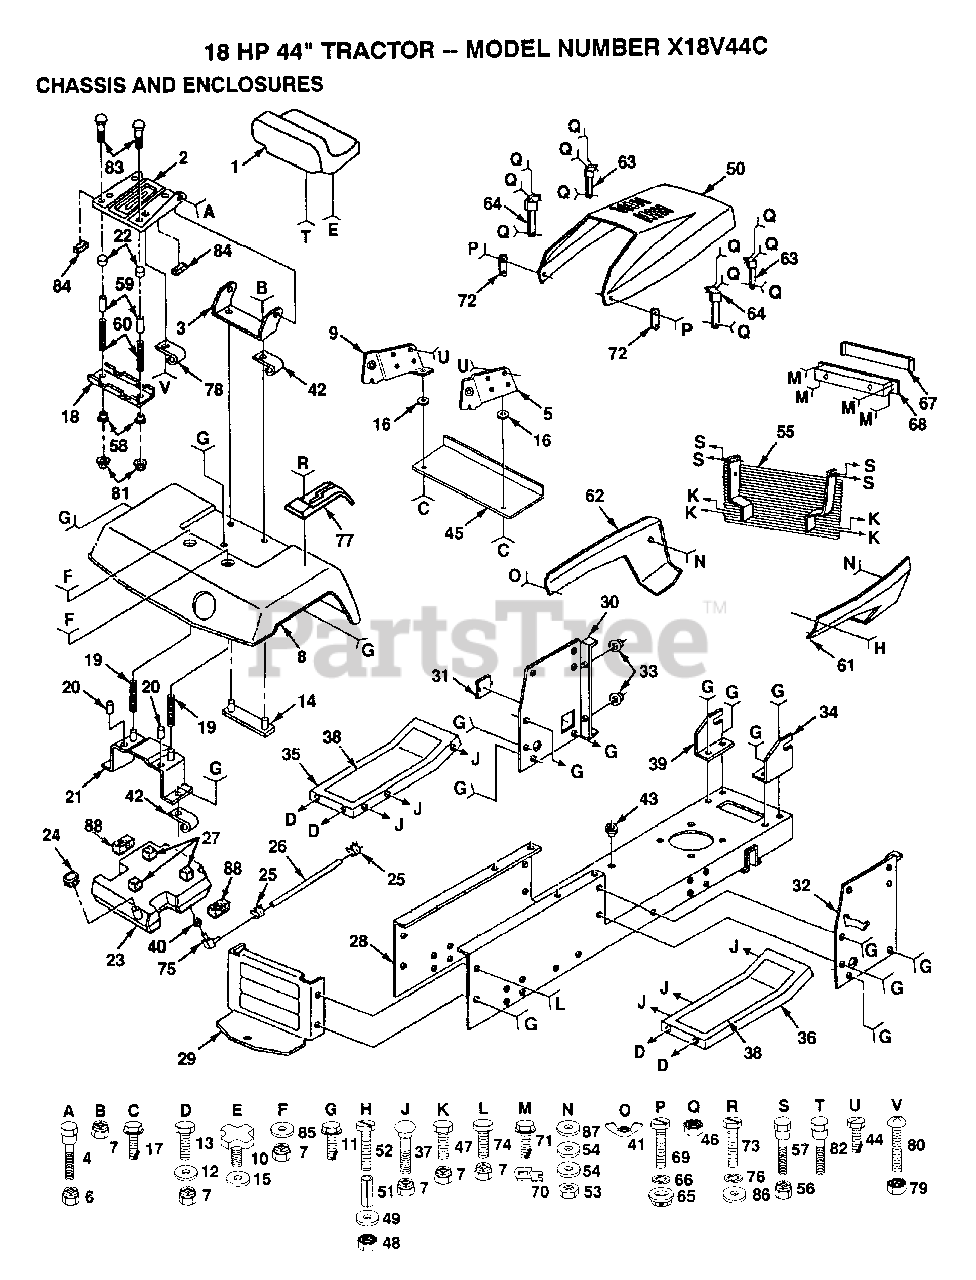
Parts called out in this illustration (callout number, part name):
5	SUPPORT RH YTH
9	SUPPORT LH YTH
10	"KNOB 1/2"" YT"
11	SCREW
12	WASHER
15	WASHER
16	WASHER
17	SCREW
18	BRKT SWITCH
19	SPRING COMPRESSIO
20	NUT-PUSH YT
22	CAP SPRING
25	HOSE CLAMP
26	FUEL LINE T
27	PAD-SPACER LT
28	CHASSIS
29	DRAW BAR
30	PANEL DASH LH
31	COVER ACCESS
32	DASH PANEL RH
33	SNAP BUSHING T
34	SUPPORT RH YTH
37	BOLT
38	FOOTREST PAD
39	SUPPORT LH YTH
40	BUSHING OUTLET T
42	CLIP T
44	SCREW
45	"STRAP,GRILL "
46	NUT
47	BOLT
49	WASHER
51	SPACER LT
52	SCREW
54	WASHER PM
58	BUSHING
59	SPACER SPLIT
60	SPRING COMPRESSED
61	"PANEL,SIDE RH "
62	"PANEL,SIDE LH "
65	WELDNUT
66	LOCKWASHER
67	LENS LT
69	SCREW
70	"""J"" FASTENER LT"
72	HOOD LATCH T
73	SCREW
75	FUEL TANK STEM GT
76	"WASHER,LOCK"
77	CONSOLE SHIFTER
79	"NUT,KEPS"
82	"BOLT,SHOULDER"
84	STRIP FORM
85	WASHER
86	WASHER
87	WASHER
88	PAD IDLER TI
